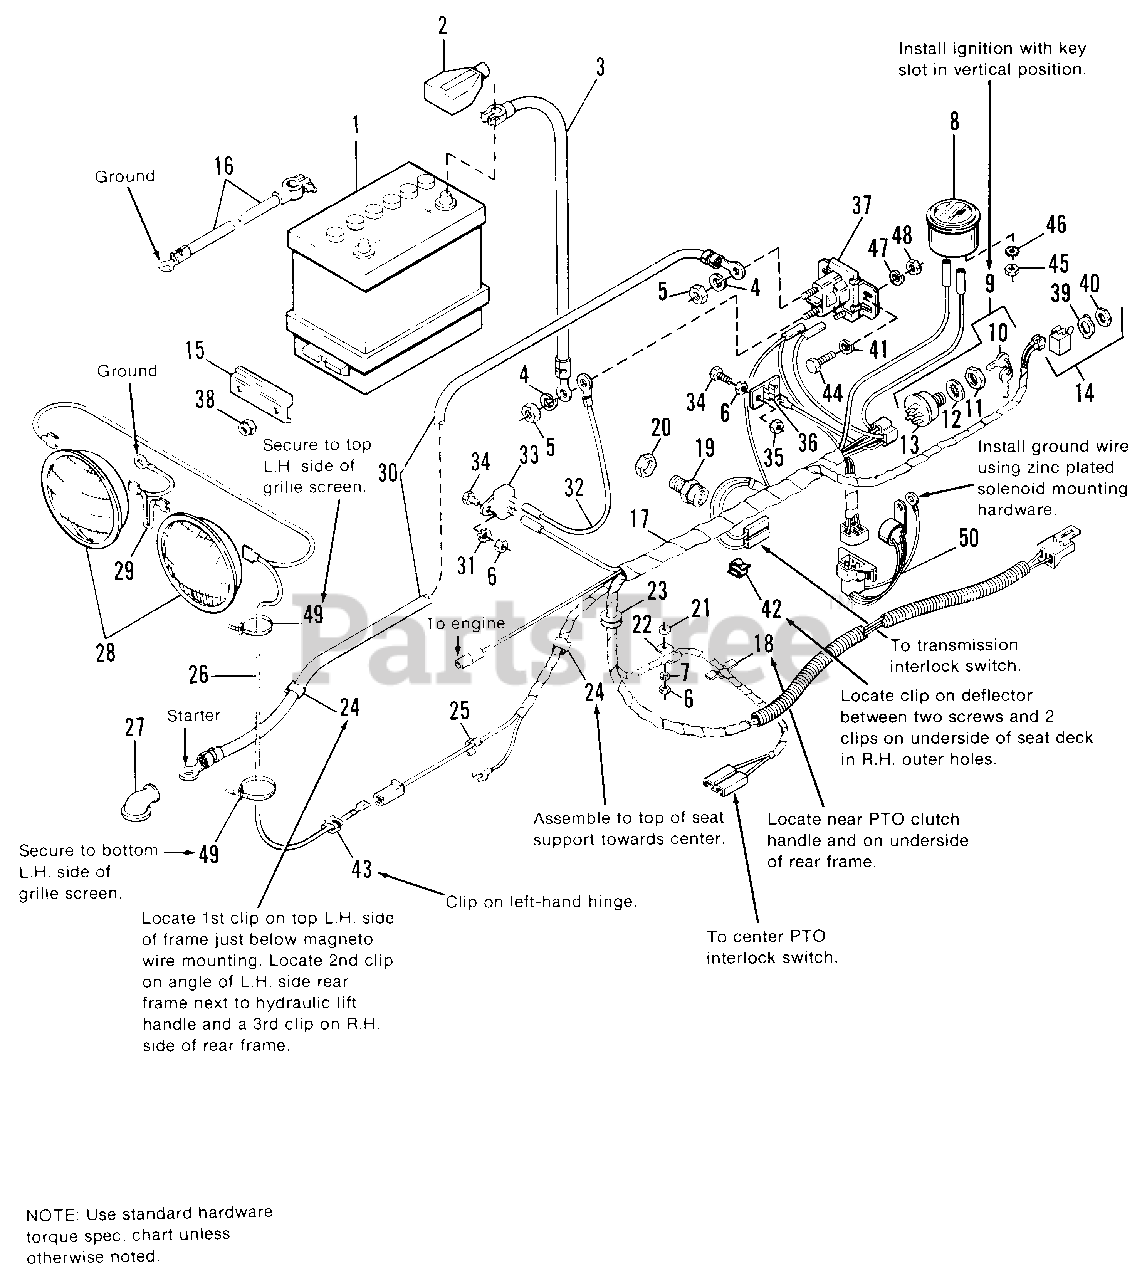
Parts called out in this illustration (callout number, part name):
1	BATTERY (Includes decal)
2	INSULATING CABLE BOOT
3	CABLE (Battery to Solenoid)
4	LOCKWASHER, 5/16
5	NUT, Hex, 5/18
6	NUT, Hex, Full, 1/4-20
7	LOCKWASHER, 1/4
9	SWITH & KEY ASSY., Ignition (Incl. Ref. Nos. 10-13)
10	KEY SET (2)
11	NUT, Special
12	LOCKWASHER, Int., 5/8
14	SWITCH, Toggle
16	CABLE (Battery to Ground)
17	HARNESS ASSY.
18	CLIP, Wire
19	SWITCH, Interlock
21	WASHER, Plain
22	CLIP, Cable
24	CLIP, Tinnerman
25	CLIP, Tinnerman
27	COVER, Terminal
28	LAMP, Sealed Beam, G.E. #4411-1
29	WIRE ASSY.
30	CABLE (Solenoid to Starter)
31	LOCKWASHER, Ext., 1/4
33	BREAKER, Circuit
34	CAPSCREW, Hex Hd., 1/4-20 x 5/8
35	LOCKNUT, Hex, 1/4-20
36	BOARD, Terminal
37	SOLENOID, Starter
38	LOCKNUT, Hex, Esna, 5/16-18
40	NUT, Switch
41	WASHER, Special, 1/4
42	CLIP, Wire
43	CLIP, Speed Cable
44	CAPSCREW, Hex Hd., 1/4-20 x 5/8 (Zinc Pltd.)
45	NUT, Hex, #10-32
46	LOCKWASHER, Ext. Tooth
47	LOCKWASHER, 1/4 (Zinc Pltd.)
48	NUT, Hex, 1/4-20 (Zinc Pltd.)
50	MODULE, Interlock
